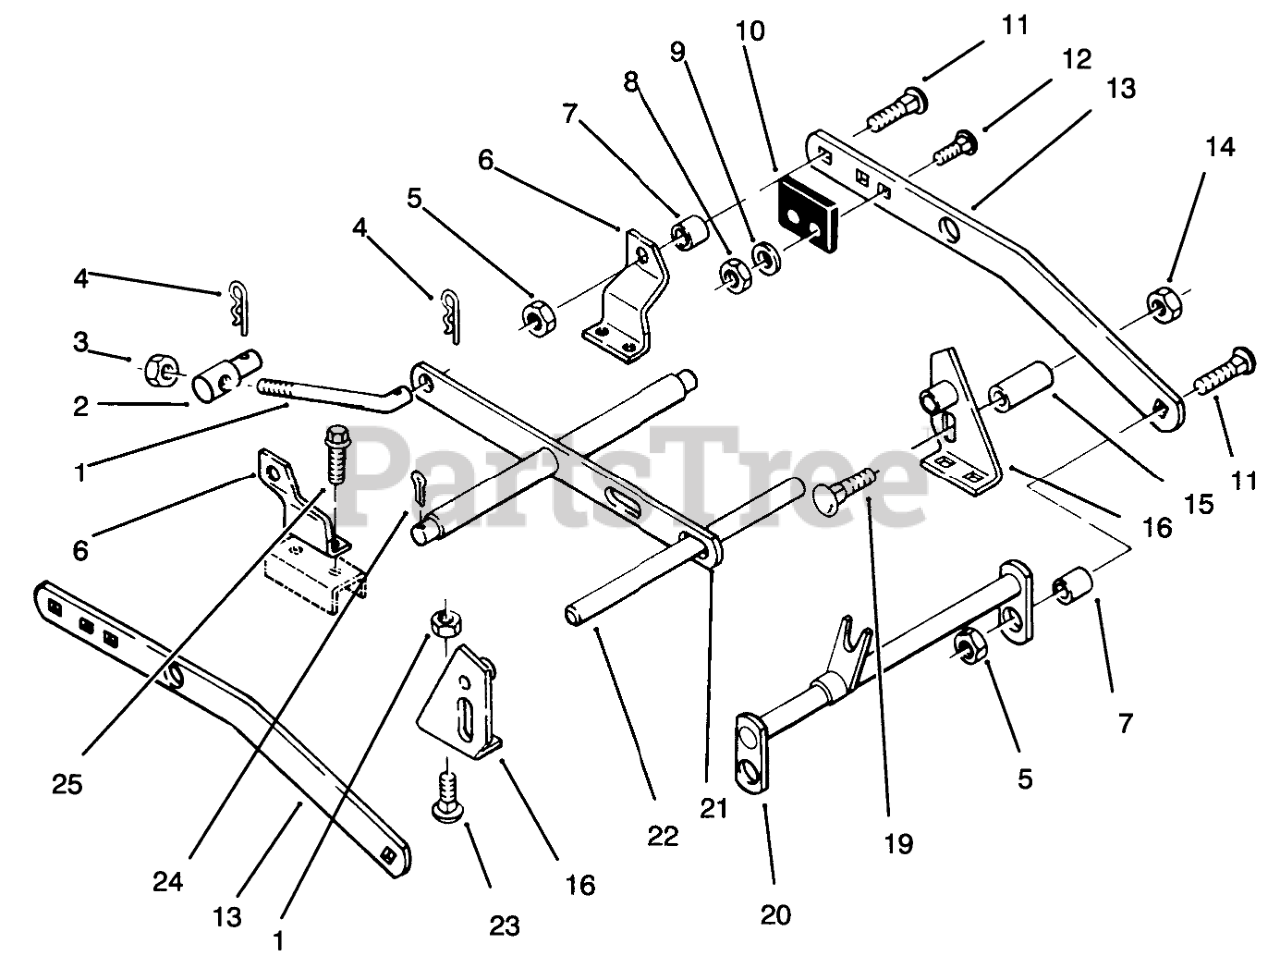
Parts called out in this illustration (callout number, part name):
1	Rod-Lift
2	TRUNNION-LIFT
3	Nut
4	PIN-HAIR
5	LOCKNUT-FLANGE
6	Bracket-Rear Deck
7	SPACER
8	NUT-LOCK, NI
9	WASHER-FLAT
10	BUMPER
11	BOLT-CARR
12	SCREW-CARR
13	Bar Draft
15	SPACER
16	BRKT-FRNT DCKR
19	SCREW-CARR
20	Hitch
21	Leveler
22	Front Shaft
23	BOLT-CARR
24	PIN-COTTER
25	SCREW-HWH, TAPTITE
